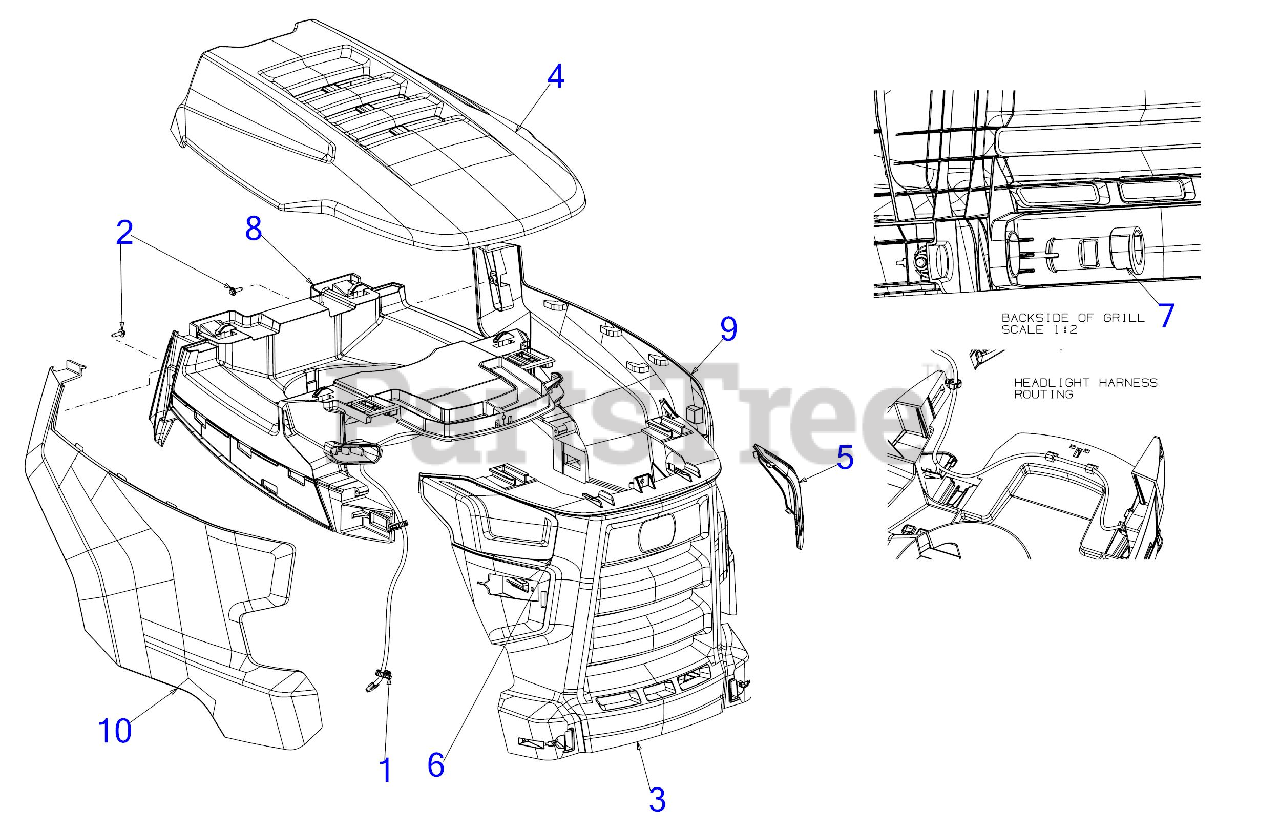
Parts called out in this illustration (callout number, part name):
1	HEADLIGHT HARNESS ASSEMBLY W/LED
2	SCREW 1/4-10 x .750
3	FRONT GRILLE (STYLE C)
4	HOOD TOP
5	HEADLIGHT LENS-LED
6	HEADLIGHT LENS-LED
7	HOOD PIVOT PIN
8	PLENUM/HOOD FRAME W/O LABEL
9	SIDE PANEL (LH)
10	SIDE PANEL (RH)
